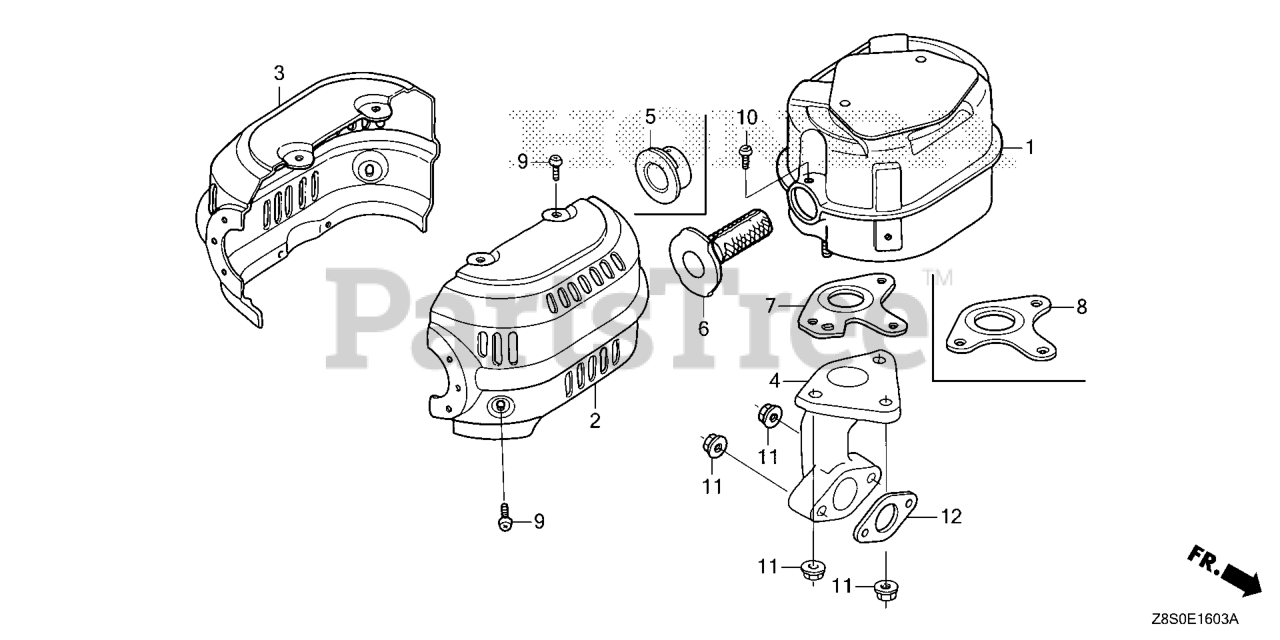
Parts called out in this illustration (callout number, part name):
1	MUFFLER
2	PROTECTOR, R. MUFFLER (STD)
3	PROTECTOR, L. MUFFLER (STD)
4	PIPE, EX.
6	ARRESTER, SPARK
7	GASKET, MUFFLER (ARRESTER)
7	GASKET, MUFFLER (ARRESTER)(THAI LEAKLESS)
9	SCREW, TAPPING (5X8)
10	SCREW, TAPPING (5X8)
11	NUT, FLANGE (8MM)
12	GASKET, EX. PIPE
